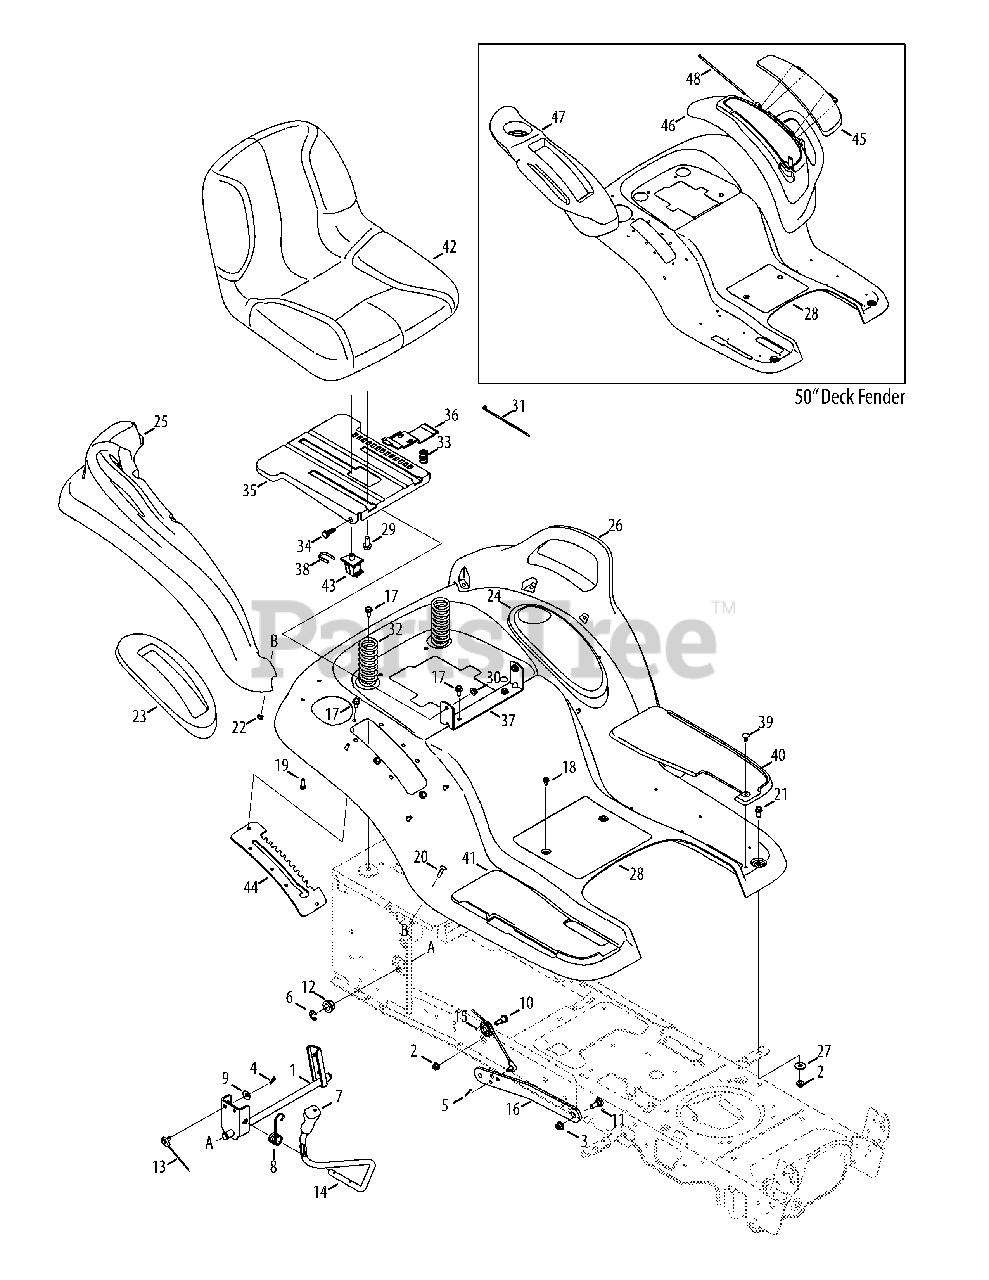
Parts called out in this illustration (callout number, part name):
1	Lift Shaft Assembly
2	Flangelock Nut, 5/16-18
3	Flangelock Nut, 3/8-16
4	Cotter Pin, .072 DIA. x 1.13 LG
5	Bow-Tie Cotter Pin
6	E-Ring, .625 DIA. SHAFT
7	Handle Grip
8	Torsion Spring
9	Spring Washer, .401 x .870 x .063
10	Shoulder Screw, .437 x .470x5/16-18
11	Shoulder Bolt, .500 x .270x3/8-16
12	Hex Flange Bearing
13	Lift Cable, 16.16 LG
14	Lift Handle
15	Pulley Roller Cable
17	Taptite Screw, Lock Washer, 5/16-18x.750
18	Taptite Screw, Lock Washer, 1/4-20
19	Hi-Lo Screw, Lock Washer, 1/4-15
20	Carriage Screw, 1/4-20x1.00
21	Taptite Screw, 5/16-18x.750
22	Sems Nut, 1/4-20
23	Lift Lever Cover
24	Cover with Cup Holder
25	RH Fender Flare
26	LH Fender Flare
27	Flat Washer, .344 x 1.00 x .063 HDN
29	Hex Head Flange, 3/8-16x.875
30	Flangelock Nut, 5/16-18
31	Cable Tie, 3/16 x .05 x 7.4
32	Compression Spring, 1.50 x 3.90 x .200
33	Compression Spring, .68 x 1.065 x .055
34	Shoulder Screw, .437 x .268x5/16-18
35	Seat Mounting Bracket
36	Seat Adjustment Lever
37	Seat Pivot Bracket
38	Switch Retainer Clip
39	Ratchet Clip
40	LH Foot Pad
41	RH Foot Pad
42	Seat
43	Seat Switch
45	Fender Cover Door
46	LH Fender Cover
47	RH Fender Cover
